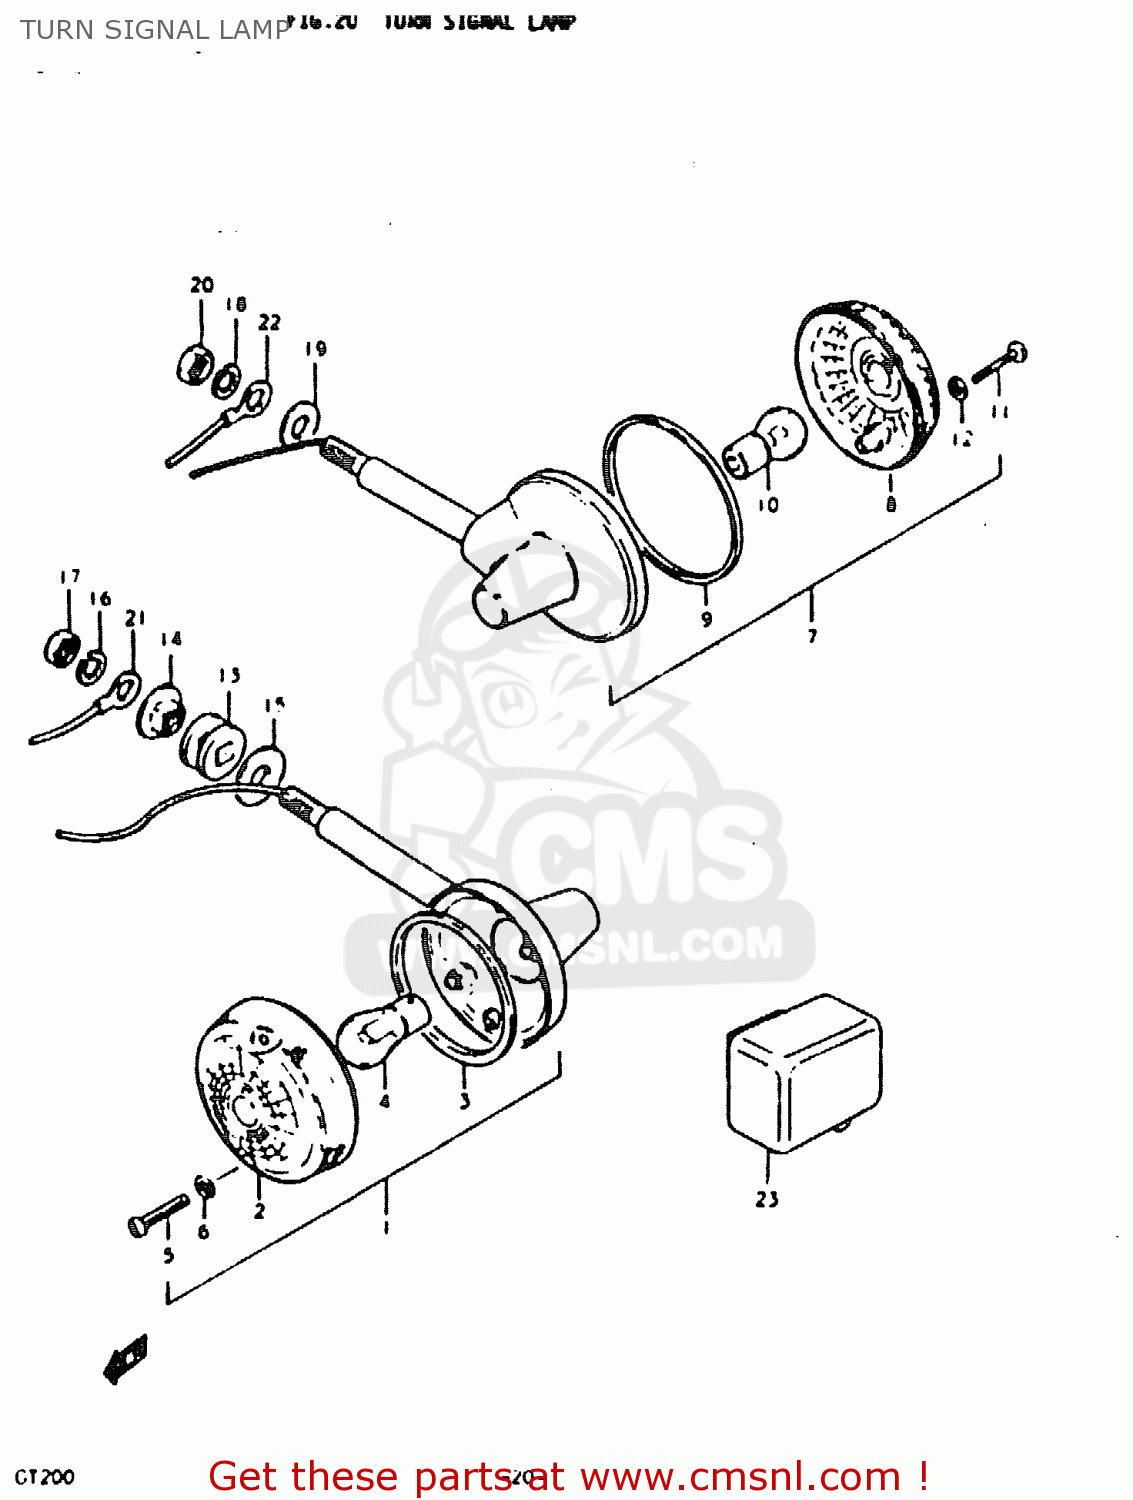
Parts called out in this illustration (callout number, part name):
1	LAMP ASSY, FRONT TURN SIGNAL
2	LENS
3	GASKET (NAS)
4	BULB(12V23W,STANLEY,A4577A)
5	SCREW
6	GASKET (NAS)
7	LAMP ASSY, REAR TURN SIGNAL
8	LENS
9	GASKET (NAS)
10	BULB(12V23W,STANLEY,A4577A)
11	SCREW
12	GASKET (NAS)
13	CUSHION
14	SPACER,RR TURNSIGNAL LAMP
15	WASHER
16	LOCK WASHER
17	NUT
18	LOCK WASHER
19	WASHER
20	NUT
22	LEAD WIRE, EARTH
23	RELAY,TURN SIGNAL
